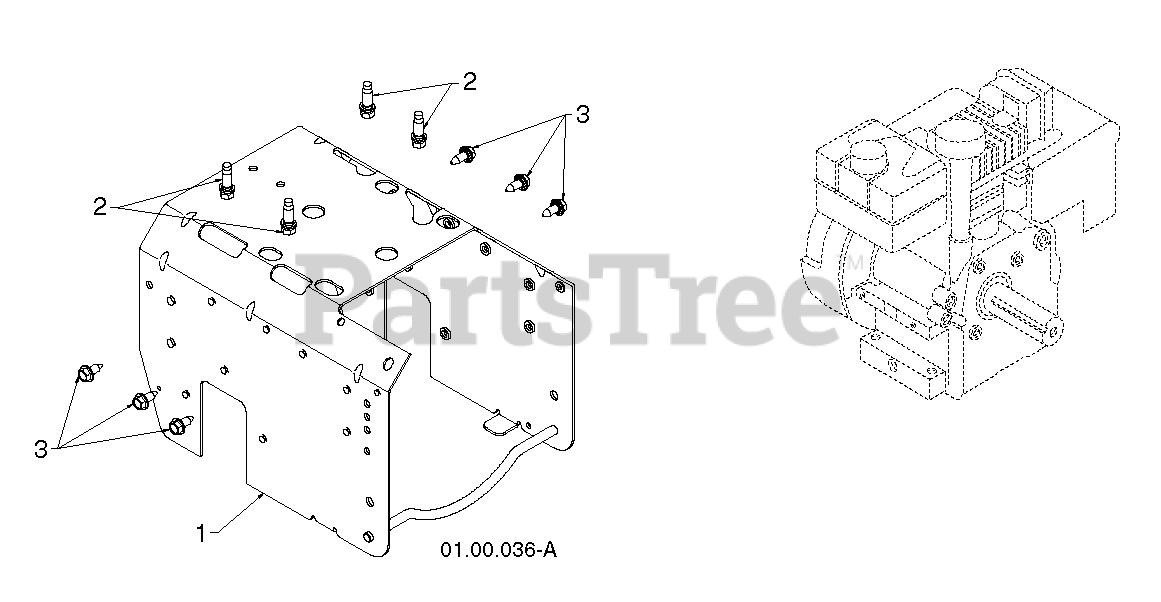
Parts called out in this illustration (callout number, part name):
1	FRAME.WELD.HYDRO.668.PNT
2	BOLT 3/8-16X1-1/8
3	BOLT.HEX.HD.WASHER.5/16-18X.75
